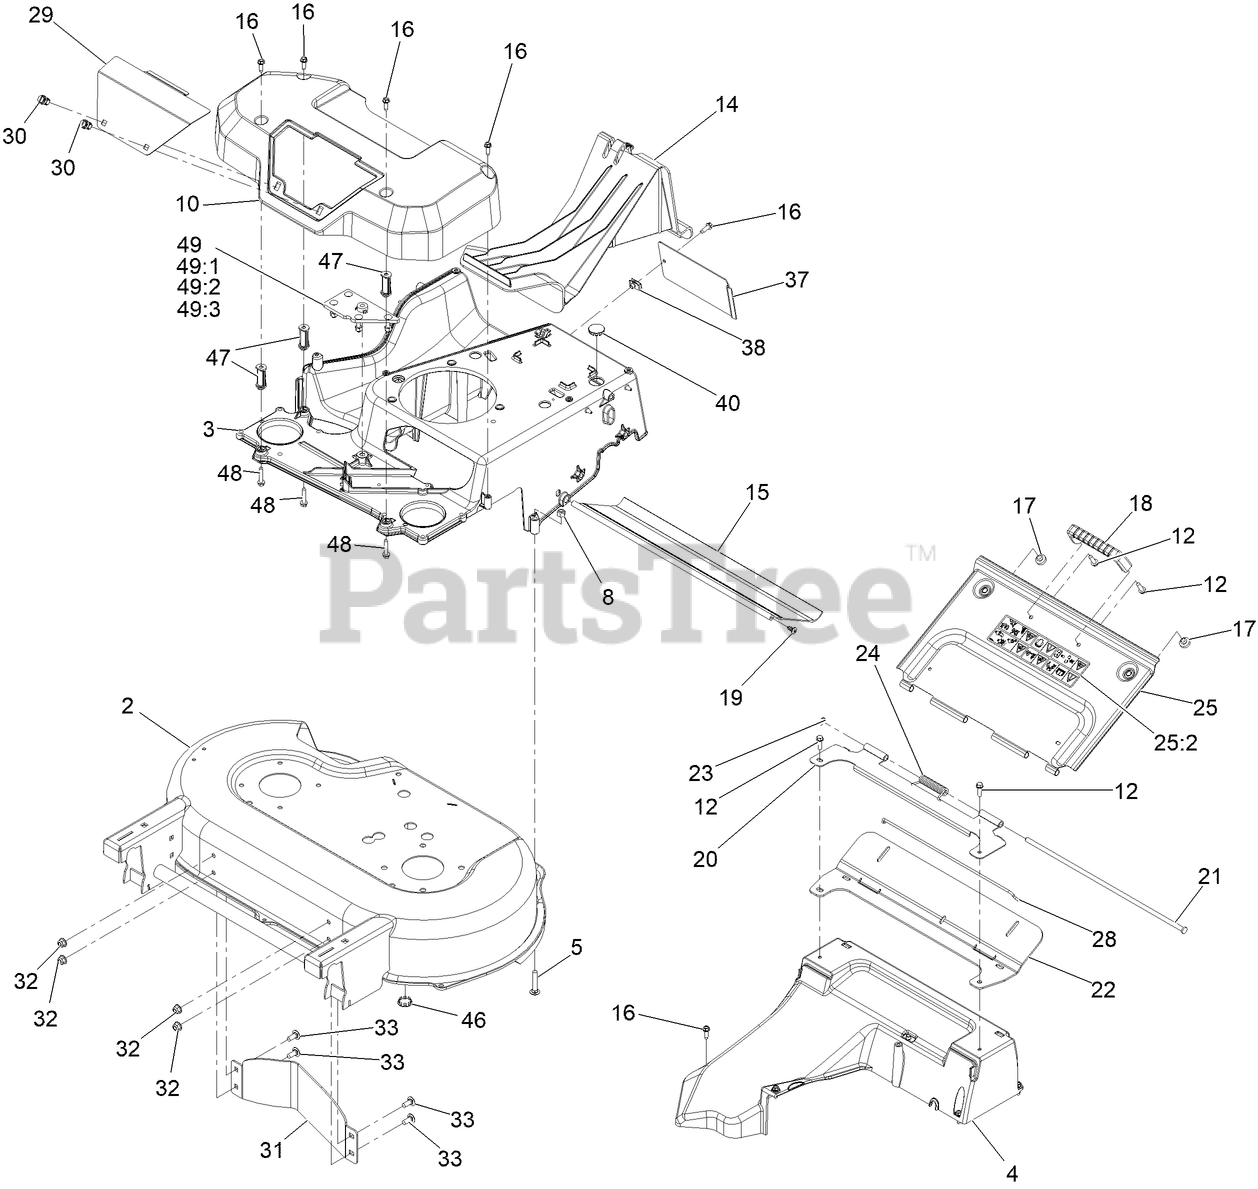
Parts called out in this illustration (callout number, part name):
2	HOUSING ASM
5	BOLT-CAR
8	NUT-LOCK, NI
10	COVER-BELT
12	SCREW-HWH
14	PLUG-MULCH
15	SHIELD-TRAILING
16	SCREW-HWHTF
18	HANDLE-DOOR
19	SCREW-PTH
20	BRACKET-HINGE
21	PIN-HINGE
22	SEAL-DOOR
23	RING-RETAINING
24	SPRING-TORSION, COVER
25	REAR DOOR ASM
25:2	DECAL-WARNING
28	CLIP-SEAL
29	PANEL-ACCESS
30	FASTENER
31	BAFFLE-CONTROL
32	NUT-HF, NI
33	SCREW-HSBH
37	Cover-Frame
40	PLUG-BUTTON
46	PLUG-BUTTON
47	SPACER-FRAME, 30 IN.
48	SCREW-HWH THD ROLL
49	FRAME-PLATE KIT
49:1	PLATE-FRAME, ASM
49:2	SCREW-CARR
49:3	NUT-LOCK, NI
